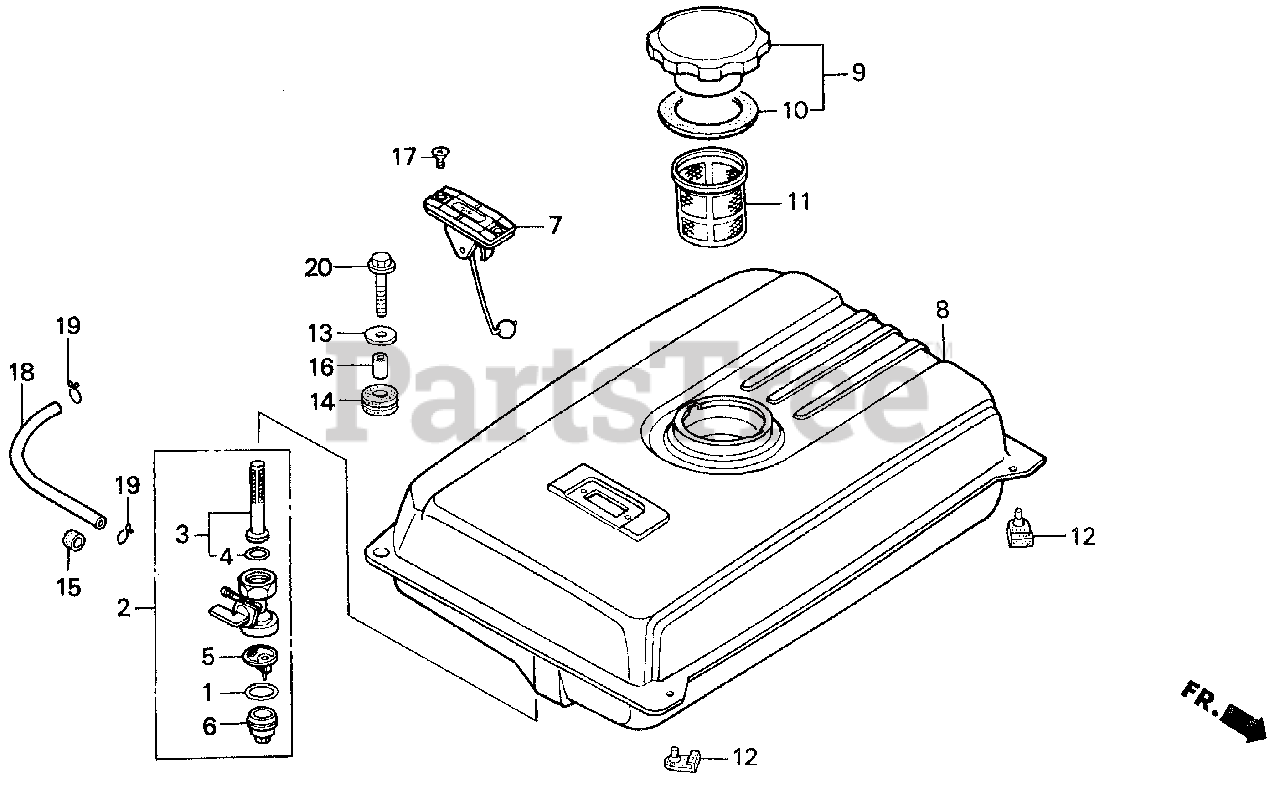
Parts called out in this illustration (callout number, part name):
1	GASKET, FUEL STRAINER CUP
2	PETCOCK ASSY.
3	SCREEN, FUEL STRAINER
4	O-RING (9X1.3)
5	FILTER, CUP
6	CUP, FUEL STRAINER
7	METER ASSY., FUEL
8	TANK, FUEL *T68* (TSURUI BLUE)
8	TANK, FUEL *Y131* (LIGHTNING YELLOW)
9	CAP, FUEL TANK
10	GASKET, FUEL FILLER CAP
11	FILTER, FUEL
12	RUBBER, TANK MOUNTING
13	WASHER, TANK RUBBER
14	CUSHION, TANK RUBBER
15	RUBBER, FUEL TUBE
16	COLLAR, TANK RUBBER
17	SCREW, FLAT (5X10)
18	BULK HOSE, FUEL (4.5X3000) (4.5X190)
18	BULK HOSE, FUEL (4.5X3000) (4.5X260)
19	CLIP, TUBE (B8)
20	BOLT, FLANGE (6X22)
